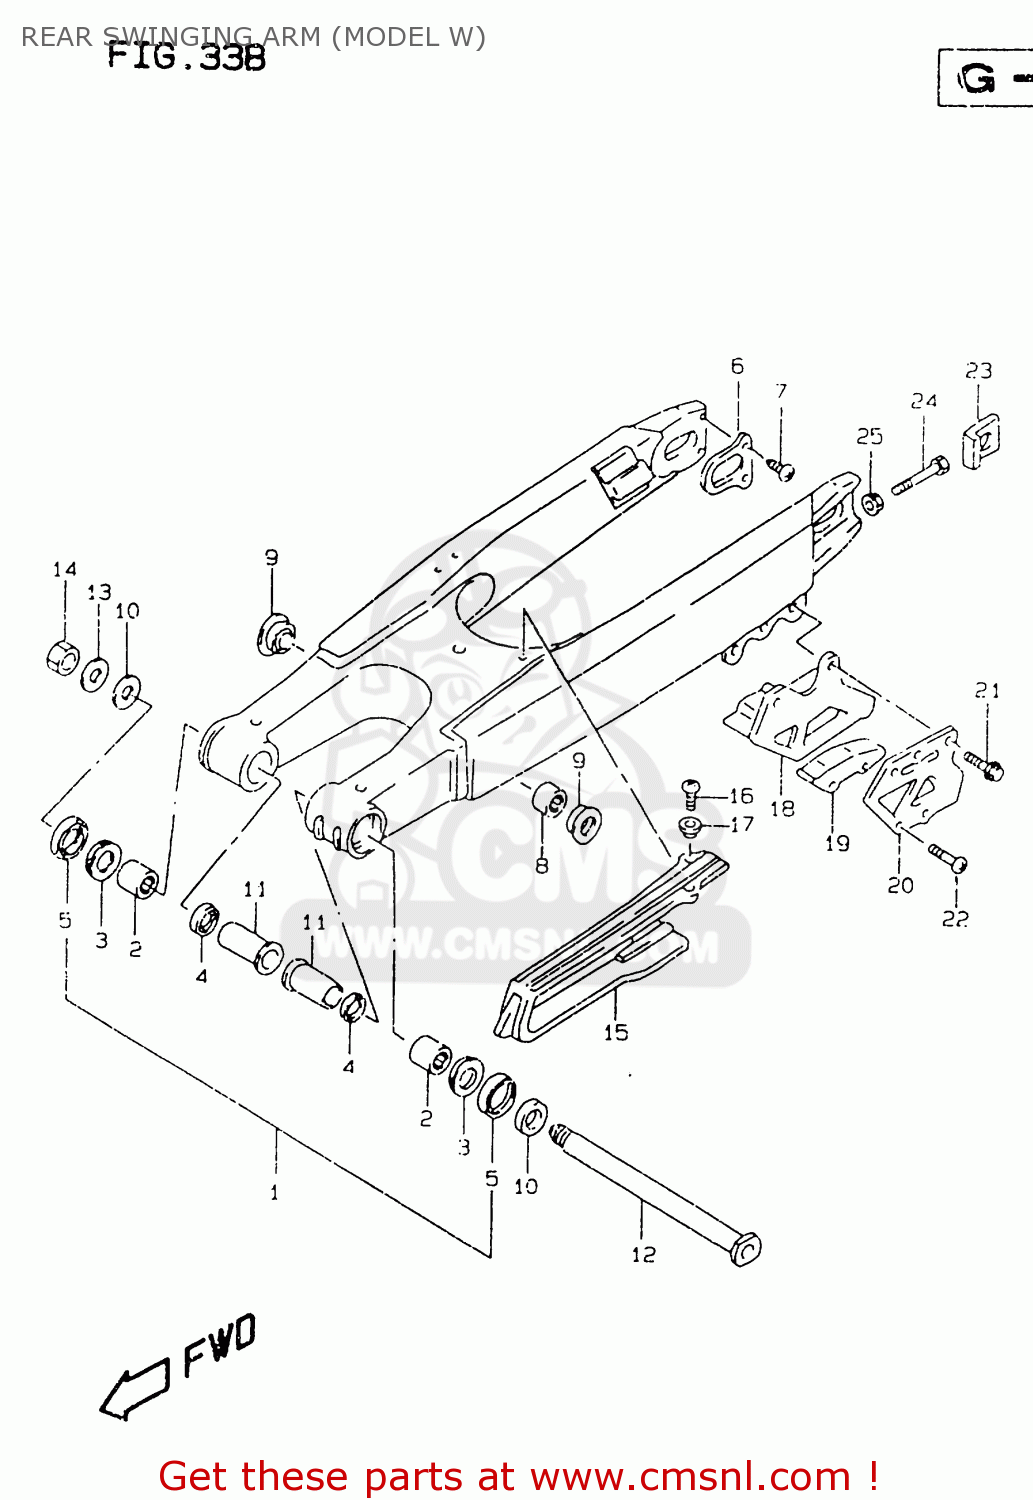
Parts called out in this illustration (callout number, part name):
1	SWING ARM ASSEMBLY,REAR
2	BEARING(22X29X30)
3	BEARING(22X35X2)
4	SEAL,OIL(22X29X4)
5	SEAL,RR SWGARM PIVOT OUTER
6	PLATE,SWING ARM RR
7	SCREW,UPPER
8	BEARING(22X28X16)
9	SEAL,SWINGING ARM RR
10	SPACER,RR SWGARM PIVOT OUTER
11	SPACER,SWGARM PIVOT INNER
12	SHAFT,RR SWINGINGARM PIVOT
13	WASHER, FIXED DRIVE FACE
14	NUT
15	BUFFER,CHAIN TOUCH DEFENSE
16	SCREW
17	WASHER
18	GUIDE,CHAIN
19	DEFENSE,CHAIN GUIDE
20	PLATE,CHAIN GUIDE OUTER
21	SCREW
22	SCREW(6X40)
23	WASHER,CHAIN ADJUSTER
24	BOLT(8X50)
25	NUT
